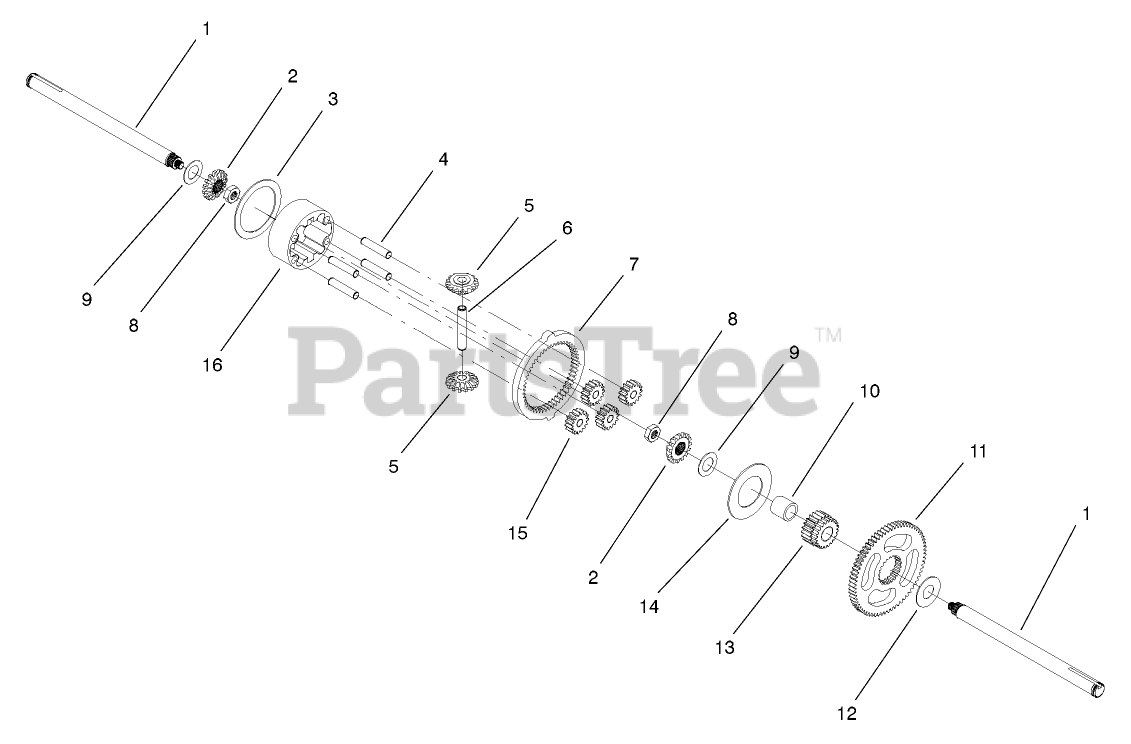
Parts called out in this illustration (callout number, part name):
1	SHAFT-AXLE
2	GEAR-MITER
3	PLATE-THRUST
4	PIN-CARRIER
5	GEAR-MITER
7	GEAR-RING, 51T
8	NUT-HJ
9	WASHER
10	BEARING-SLEEVE
11	GEAR-SPUR, 67T
12	WASHER
13	GEAR-SUN, 21T
14	PLATE-THRUST, PLANET
15	GEAR-PLANET, 15T
16	CARRIER-PLANETARY
